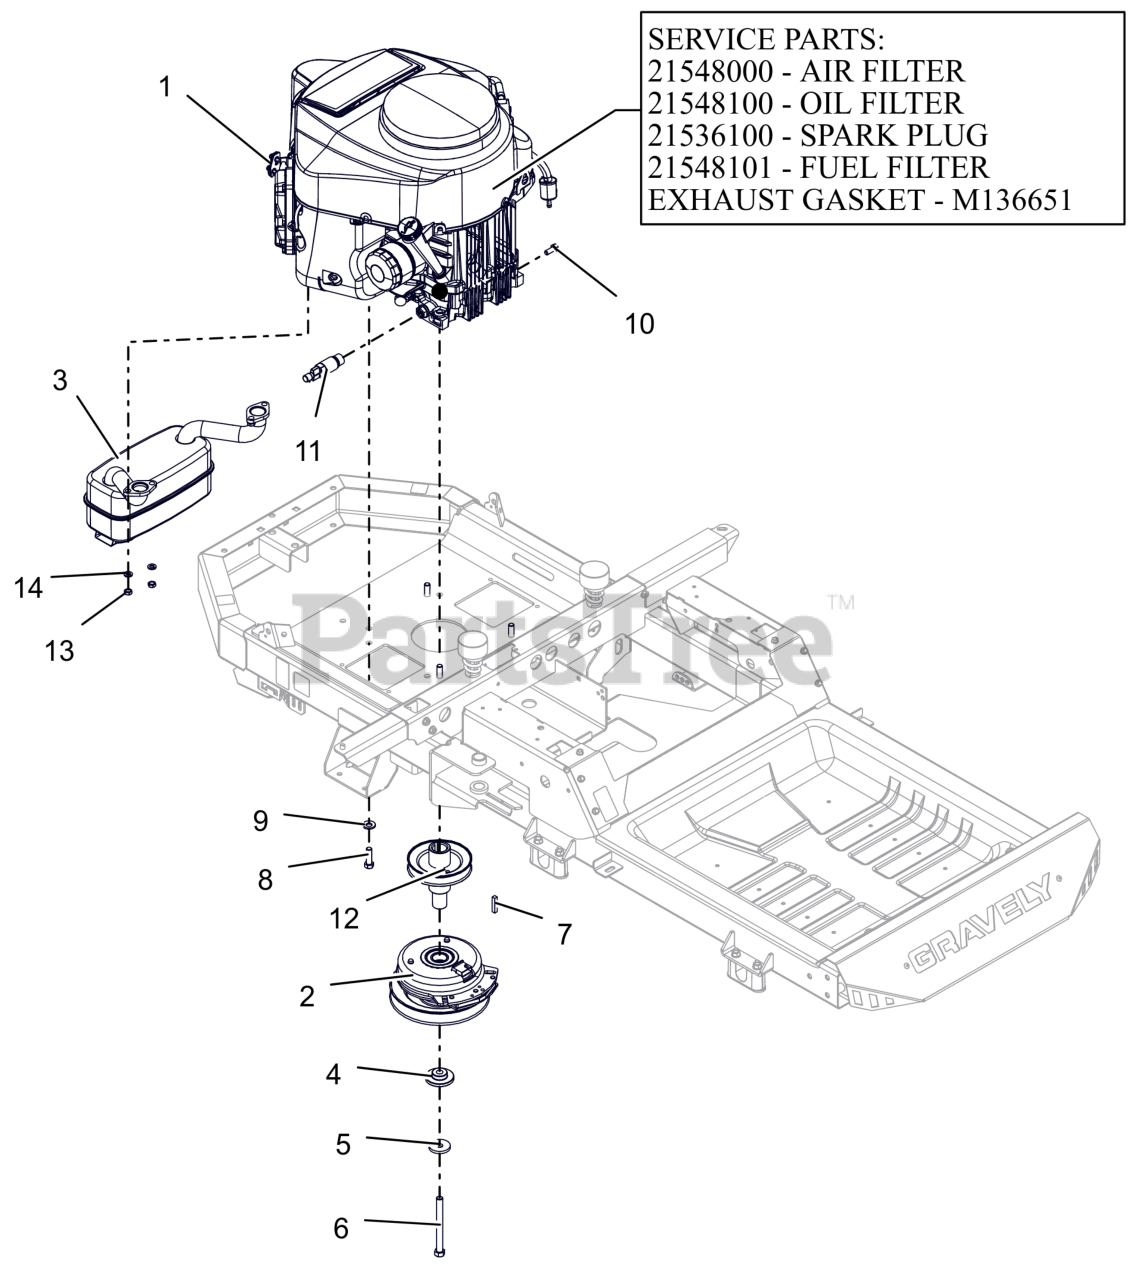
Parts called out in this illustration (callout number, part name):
1	ENGINE, KAWASAKI FR691 23HP
1	AIR FILTER, KAWASAKI FR
1	OIL FILTER, KAWASAKI FR
1	PLUG, SPARK
1	FUEL FILTER-KAWASAKI FR
1	GASKET, MUFFLER #
2	CLUTCH,105FTLB MONOPOLE 6.83"
3	MUFFLER - KAWASAKI
4	BSHG-FLG .469X1.06X.574X2.0
5	WASHER, 7/16" SPRING DISK
6	BLT, HEX .44-20X4.50 G8 ZCC NT
7	KEY-SQ .25 X 1.25 X .25 SAE
8	BLT, HEX .38-16X1.25 G5 ZCC NT
9	WASHER, 3/8" SPRING DISC
10	BLT, HEX M8-1.25X20 G8.8 ZCC
11	DRAIN, OIL M20X2.5
12	WLDMT, DRIVE SHEAVE-X
13	NUT,NYL M8-1.25 G8.8 ZCC
14	WSHR,LK-REG .312X.078 ZCC
